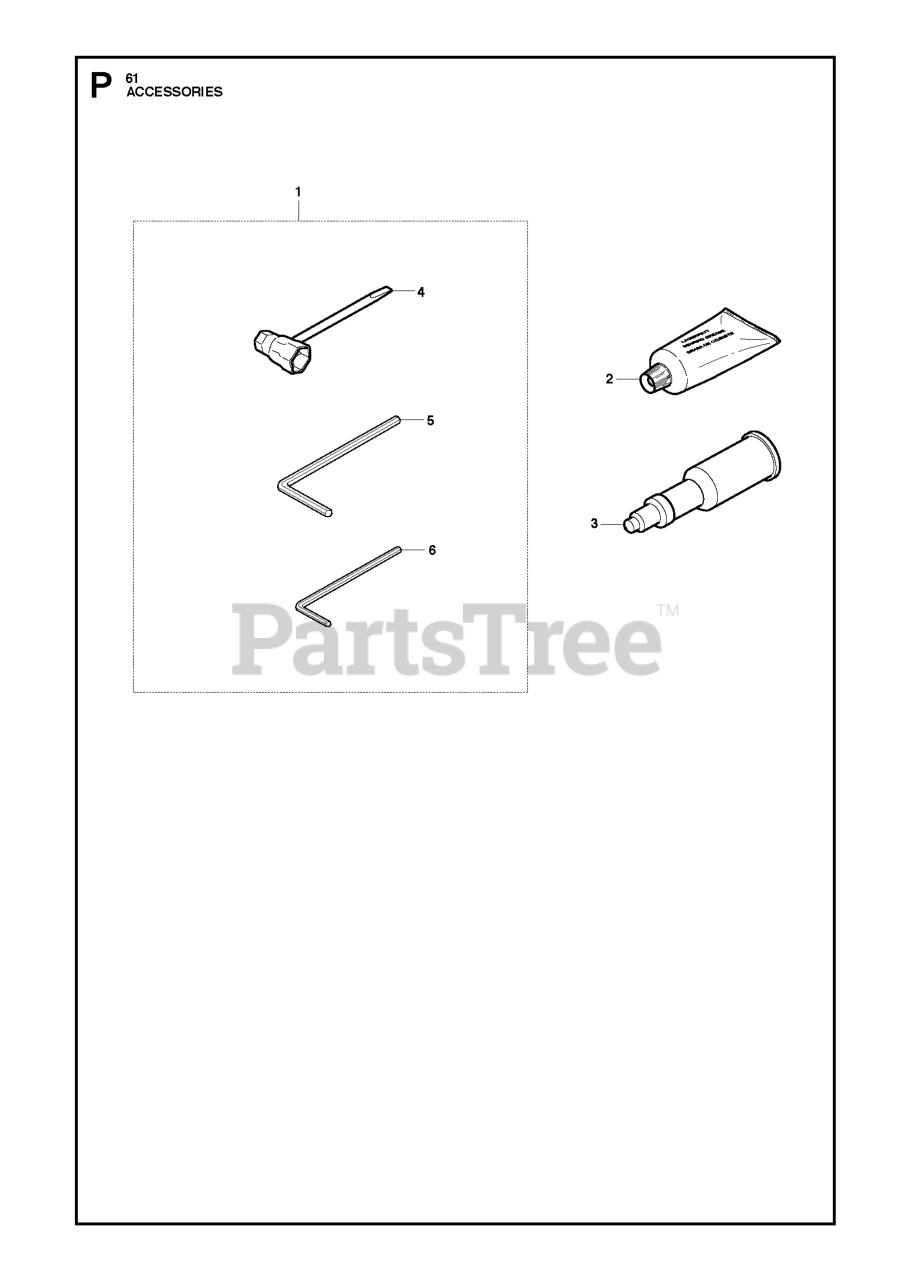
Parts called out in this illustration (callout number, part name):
1	TOOL KIT
2	GREASE
3	Grease Gun
4	COMBI TOOL
